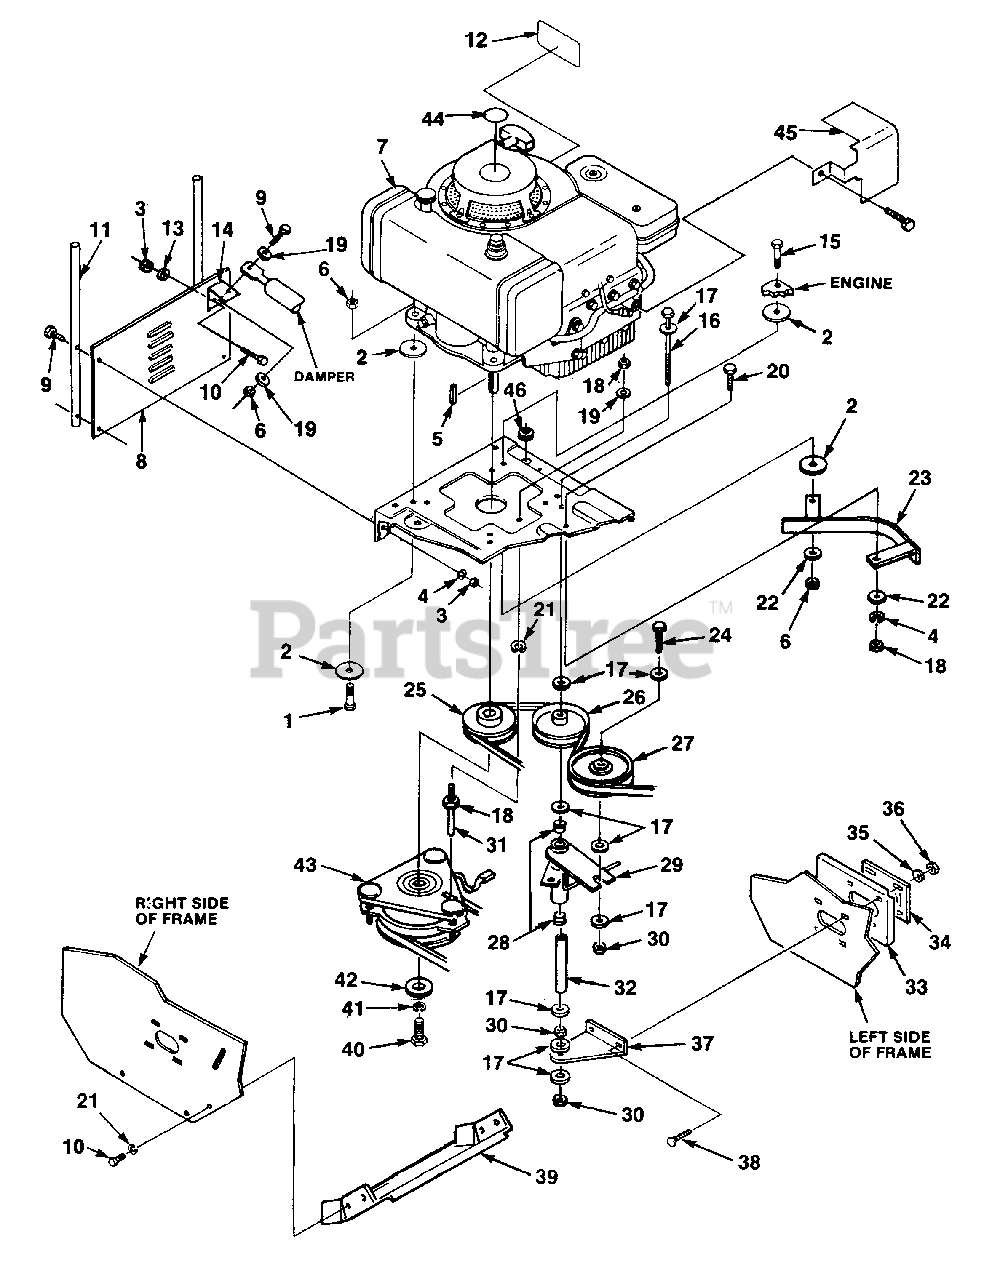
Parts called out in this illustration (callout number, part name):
1	SCREW- 5/16-18 x 1 1/2
2	WASHER- 5/16
3	NUT- 1/4-20 hex
4	WASHER- 1/4
5	KEY- 1/4 x 1/4 x 1
6	NUT- Lock 5/16 x 18
7	ENGINE-
8	PANEL- Rear
9	BOLT- 5/16-18 x 3/4
10	SCREW- 1/4-20 x 5/8
11	TUBE- Catcher Support
12	DECAL- (Hot Muffler)
13	WASHER
15	BOLT- 5/16-18 x 1 3/4
16	BOLT- 3/8-16 x 5 1/2
17	WASHER- 3/8 flat
18	NUT- Hex 1/4-20
19	WASHER- Flat 5/16
20	BOLT- 1/4-20 x.750
21	WASHER- Lock 5/16
22	WASHER- Flat 1/4
23	GUIDE- Belt
24	BOLT- 3/8-16 x 1 3/4
25	PULLEY- Engine
26	PULLEY- Idler
27	PULLEY- Idler
28	BEARING- Flange
29	ARM- Pivot
30	NUT- Hex Centerlock 3/8-16
31	PIN- Clutch torque
33	SUPPORT- Frame
34	RETAINER & BEARING
35	WASHER- Lock 114 hvy
36	NUT- Centerlock hex 1/4-20
38	BOLT- Rd. hd. carr. 1/4-20 x.750
39	PAN- Bottom
40	BOLT- Hex hd. 7/16-20 x 2 3/4
41	WASHER- Lock 7/16
42	CLUTCH RETAINER
43	CLUTCH- Warner
44	DECAL- 8 H.P.
45	HEAT SHIELD
